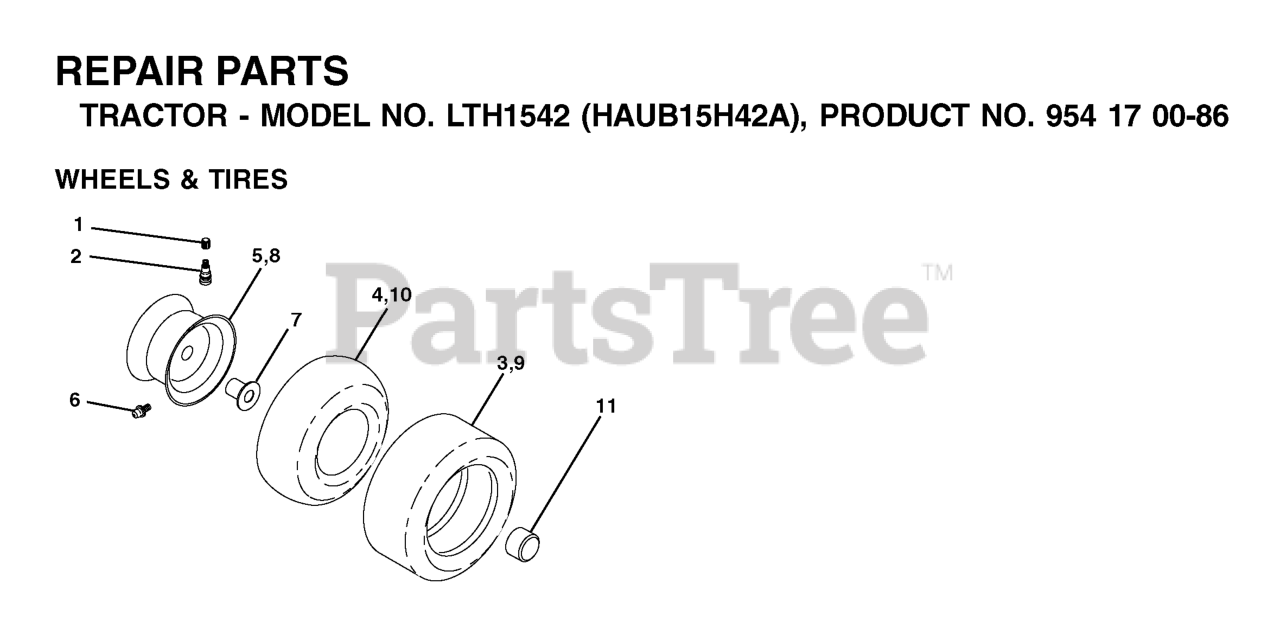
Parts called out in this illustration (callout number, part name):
1	SCREW 3/8C X 2 3/4 HEX CAP
2	IDLER PULLEY
3	IDLER BUSHING
4	MANDREL ASM
5	STRIPPER-ROUND-UNIVERSAL
6	48" HI-LIFT BLADE
7	WASHER-SPACER
8	PULLEY.DRIVEN.DECK.48'
9	BOLT 7/16 ASM BLADE
10	LOCKNUT - 9/16
11	IDLER SPINDLE
12	NUT 1/2-13 HEX NYLOC ZD
13	SCREW, 1/2C X 3 HEX CAP
15	WASHER, SUPPORT
16	DECK IDLER ARM
17	WASHER 1/2 FLAT
18	4CS 3/8C X 1 SERRATED HEAD
19	WASHER 5/16 FLAT
20	DEFLECTOR.ASM.BLACK.48"
21	BOLT, SHOULDER
22	TORSION SPRING
23	WHEEL GAGE DONUT
24	NOSE ROLLER 48"
25	NOSE ROLLER ROD
26	VORTEX MOWER BAFFLE
27	PIVOT BUSHING
28	PULLEY.IDLER.FLAT.46.PR.DR.
29	PUSH NUT
30	CAP-SLEEVE
31	WASHER HEAD SCREW
32	SCREW- 1/4-20 X 5/8
33	TENSION RELIEF LINKAGE
34	BELT SHIELD
35	TENSION RELIEF LEVER BLK
37	BELT, DECK
38	ROD.HINGE
39	DECK SVC W/DECALS HUSQ ORANGE
40	DECAL, BELT ROUTING
41	CARRIAGE BOLT 5/16C X 5/8"
42	DECAL, CPSC
43	NUT 3/8-16 NYLOC
44	WASHER 3/8 SAE FLAT
45	NUT 5/16C HEX
46	RHSNB 5/16C X 1
47	RP_COTTER PIN 1/8 X 3/4
48	NUT 5/16 NYLOC
49	HCS 3/8-16 X 1 3/4 GR5
